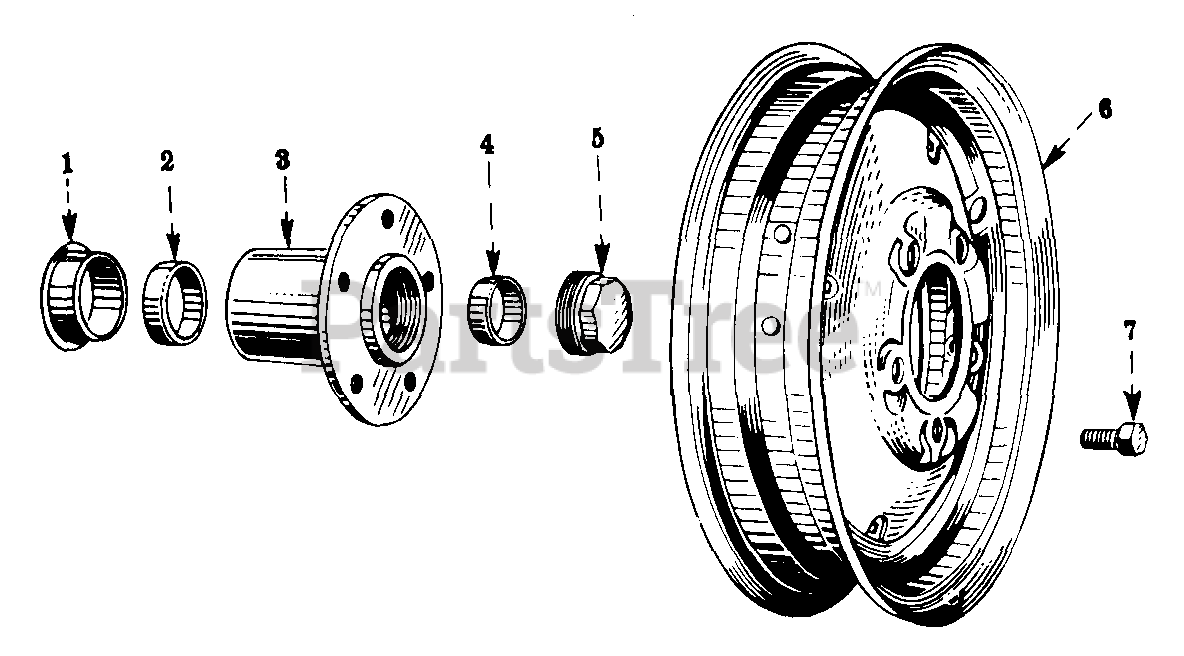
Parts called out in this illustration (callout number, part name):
1	RING, WEAR FRONT WHEEL OIL SEAL
2	BEARING, FRONT WHEEL INNER CUP
3	HUB ASSY, FRONT WHEEL
4	BEARING, FRONT WHEEL OUTER CUP
5	CAP, FRONT WHEEL HUB
6	WHEEL ASSY
7	BOLT, FRONT WHEEL HUB
